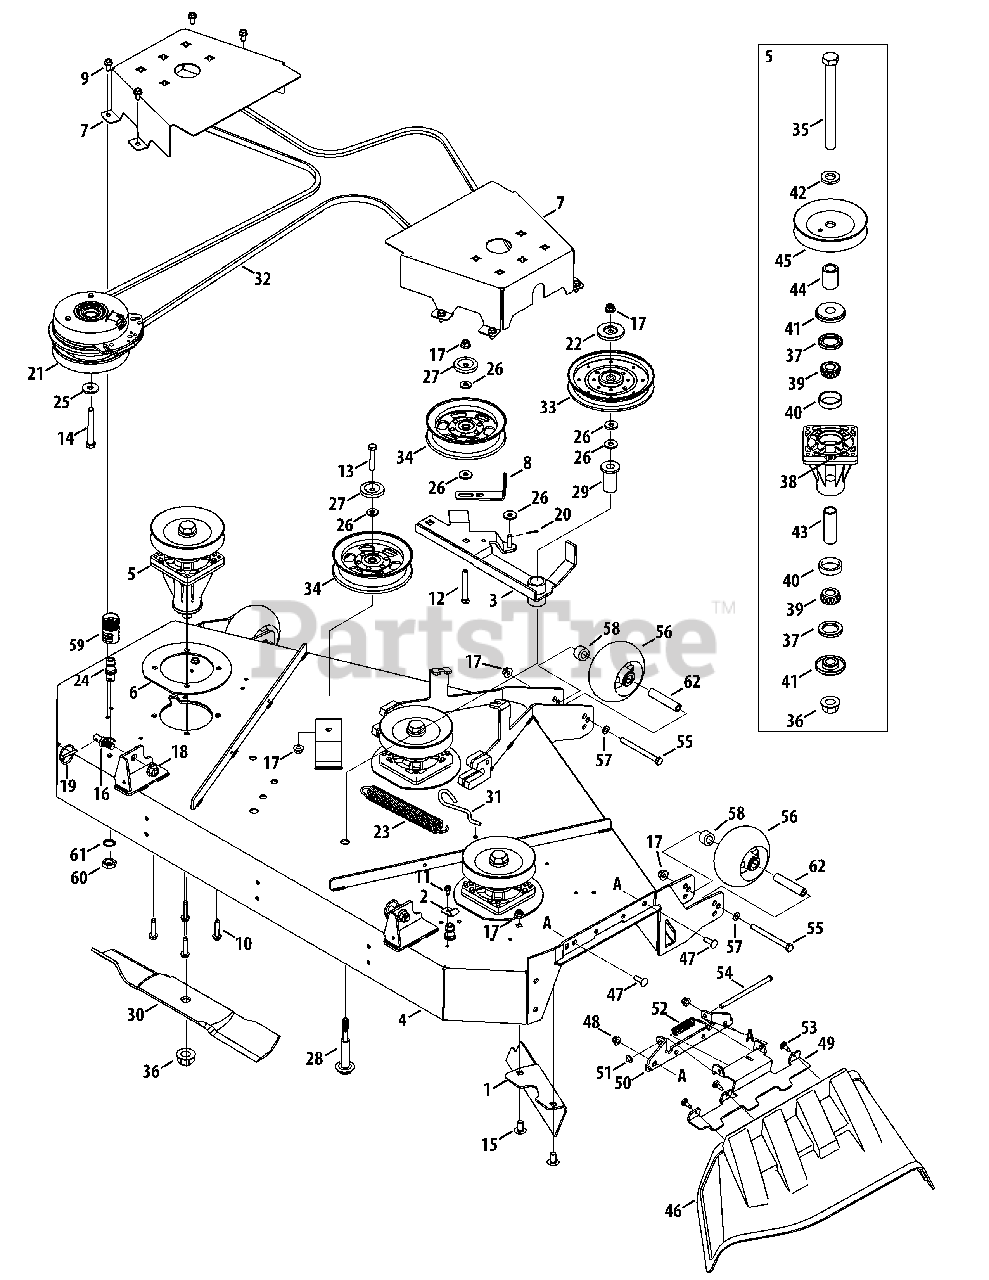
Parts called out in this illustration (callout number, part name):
1	Chute Baffle
2	Bracket, Hook Retainer
3	Deck Idler Assembly
4	60" Deck
5	Spindle Assembly
6	Spindle Reinforcement Plate
7	Belt Cover
8	Bracket, Deck Keeper
9	Hex Washer Screw, 5/16-18 x .750
10	Hex Washer Screw, 5/16-18 x 1.50
11	Hex Washer Screw, 1/4-20 x .500
12	Hex Cap Screw, 3/8-16 x 2.50
13	Hex Cap Screw, 3/8-16 x 2.00
14	Screw, 7/16-20 x 3.25
15	Carriage Screw, 3/8-16 x .75
16	Pin, Shoulder Lock, .500
17	Flange Lock Nut, 3/8-16
18	Flange Lock Nut, 1/2-13
19	Pin, Lynch x .1875
20	Cotter Pin 3/32" Dia. x .75 Lg.
21	Electric PTO Clutch
22	Pulley Cap
23	Extension Spring, 1.25 OD x 1.751
24	Deck Water Nozzle
25	Flat Washer, .450 x 1.25 x .164
26	Flat Washer, .406 x .875 x .105
27	Pulley Cap
28	Shoulder Boult, .625 x 2.12, 3/8-16
29	Shoulder Spacer, 1.055 x .627 x 2.292
30	Blade, 21.00
31	Deck Spring Rod
32	V-Belt
33	Idler Pulley, 6.00 Dia
34	Idler Pulley, 5.00 Dia.
35	Hex Cap Screw, 3/4-16 x 8.25
36	Nut, 3/4-16, Flangelock
37	Oil Seal
38	Grease Fitting
39	Cone Bearing
40	Cup Bearing
41	Spindle Spacer
42	Spacer, .812 ID x .218 LG
43	Spacer, .78 x 1.00 x 2.895
44	Spacer, .792 x 1.20 x 1.628
45	V-Type Pulley
46	Discharge Chute Assembly
47	Carriage Bolt, 5/16-18 x 1.00
48	Flange Lock Nut, 5/16-18
49	Chute Bracket
51	Push Cap
52	Torsion Spring
53	Shoulder Screw, 1/4-20
54	Chute Rod
55	Hex Cap Screw, 3/8-16 x 4.0
56	Deck Ball Wheel, 5.0
57	Flat Washer, .406 x .875 x .059
58	Shoulder Spacer, .500 x 3.09
59	Water Nozzle Adapter
60	Hex Nut, M-16 x 1.5
61	Lock Washer, 17 x 23.8 x 1.95
62	Spacer, .380 x .495 x 3.450
